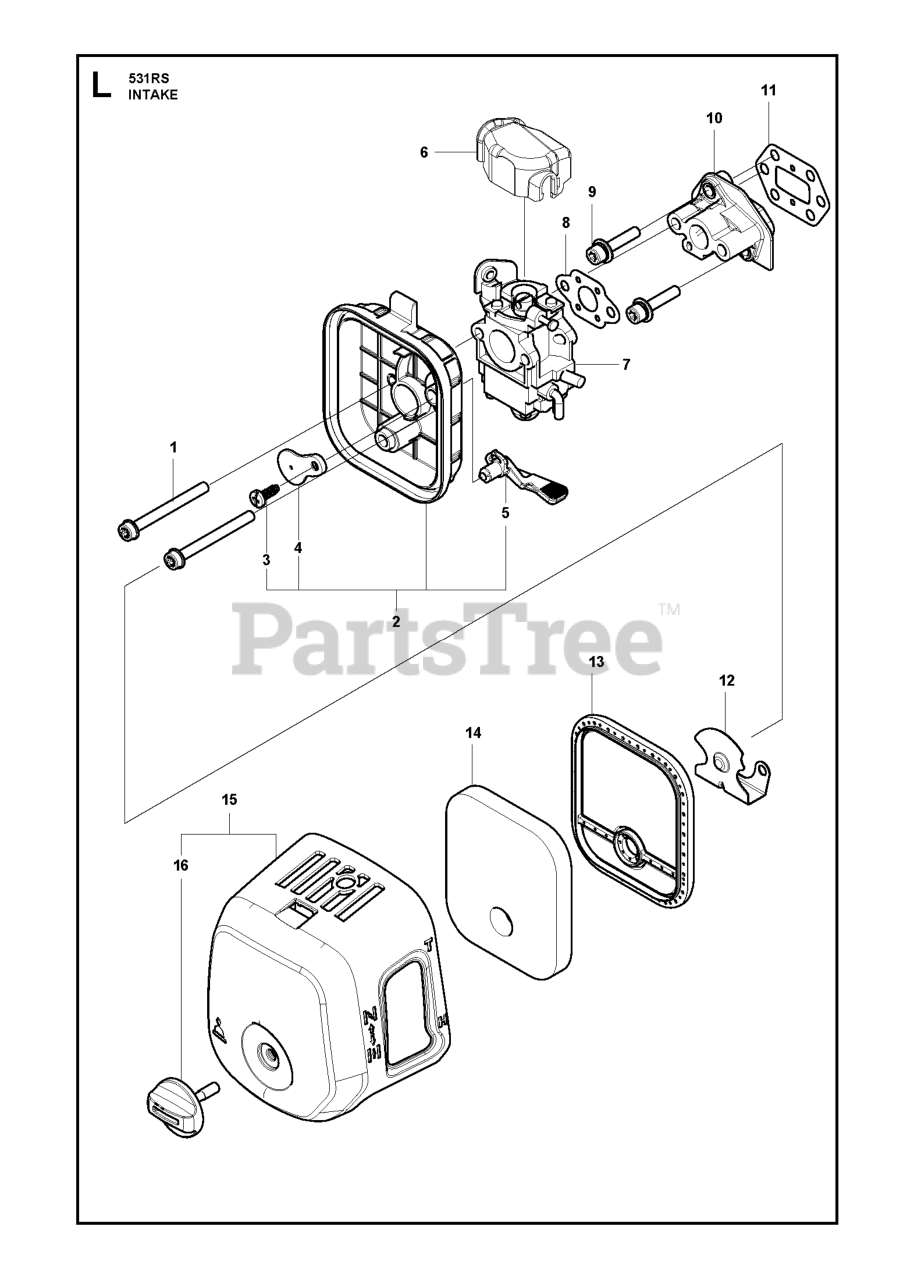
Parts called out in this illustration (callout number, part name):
3	SCREW
4	PLATE, CHOKE
9	BOLT M5X25
